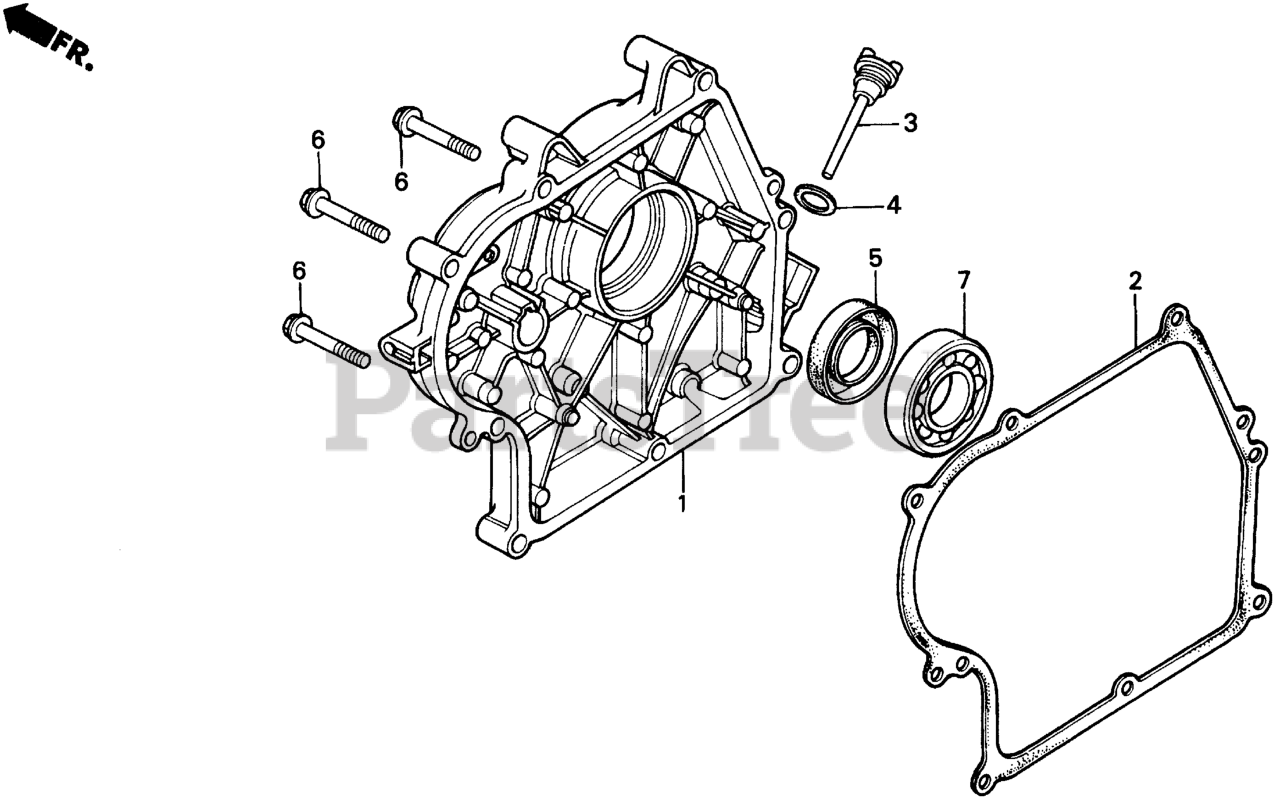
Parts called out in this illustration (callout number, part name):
1	COVER, CRANKCASE
2	GASKET, CASE COVER
3	CAP, OIL FILLER
4	GASKET, OIL FILLER CAP Use from Engine SN 1391010.
5	OIL SEAL (30X46X8)
6	BOLT, FLANGE (8X40)
7	BEARING, RADIAL BALL (6206)
